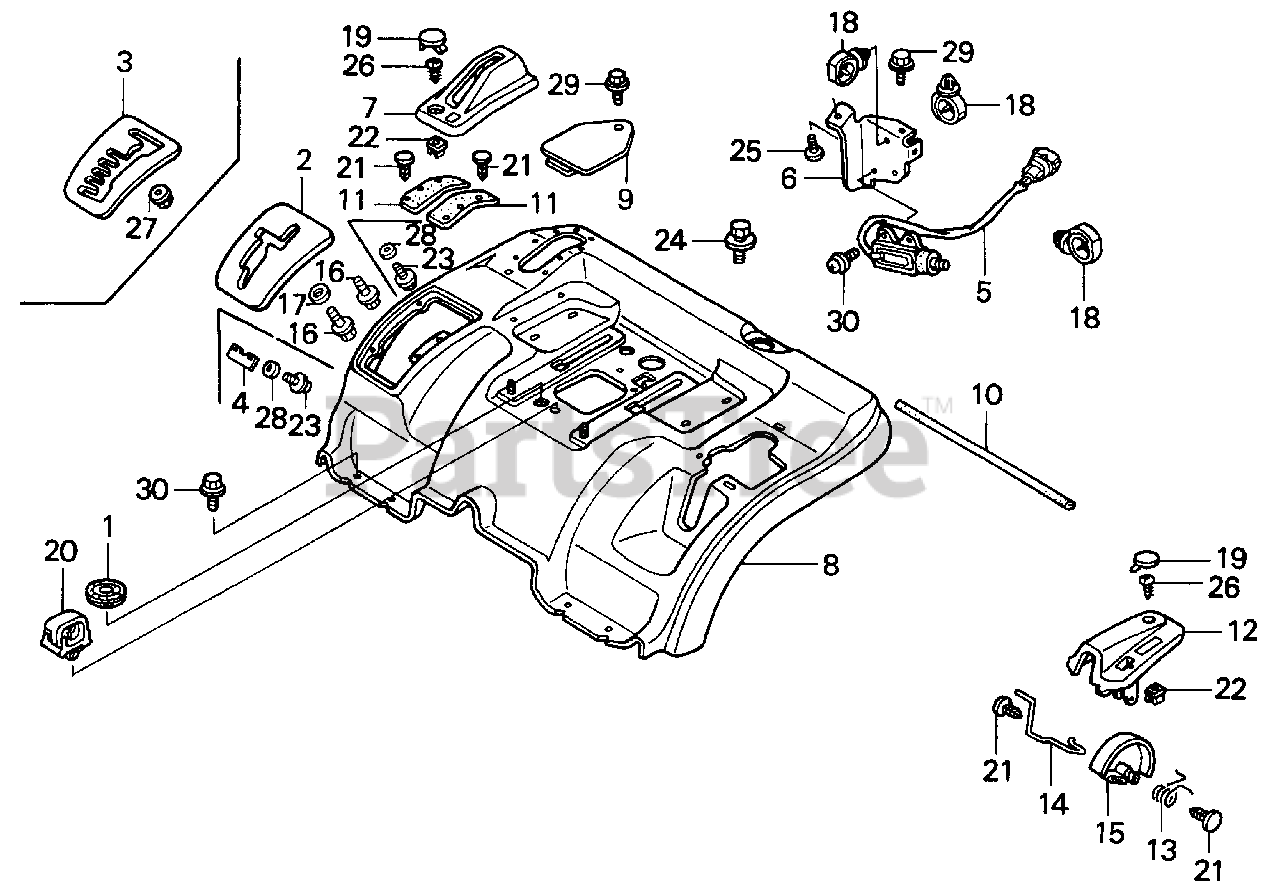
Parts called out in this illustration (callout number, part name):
1	GROMMET, WIRE
2	GUIDE, CHANGE LEVER *R165* (JOLLY RED)
5	SWITCH ASSY., NEUTRAL
6	PLATE, NEUTRAL SWITCH
7	PROTECTOR, PARKING BRAKE LEVER *NH247* (ASSEMBLY GRAY)
8	FENDER, RR. *R165* (JOLLY RED)
9	PANEL, FENDER COVER
10	TRIM, RR. FENDER
12	PROTECTOR, HEIGHT ADJUSTING LEVER *NH247* (ASSEMBLY GRAY)
13	SPRING, INDICATOR
14	ROD, INDICATOR
15	INDICATOR, HEIGHT
16	BOLT-WASHER (5X8)
17	WASHER (6MM)
18	CLIP, HARNESS
19	CAP, LINING *NH120L* (STAR BLACK)
19	CAP, LINING *NH1L* (BLACK)
20	CLIP, HARNESS (7MM)
21	CLIP, COVER (5MM)
22	GROMMET, SCREW (5MM)
24	BOLT-WASHER (8X16)
25	BOLT, FLANGE (6X8)
26	SCREW, TAPPING (5X12)
29	BOLT, FLANGE (6X12)
30	BOLT, FLANGE (6X12)
